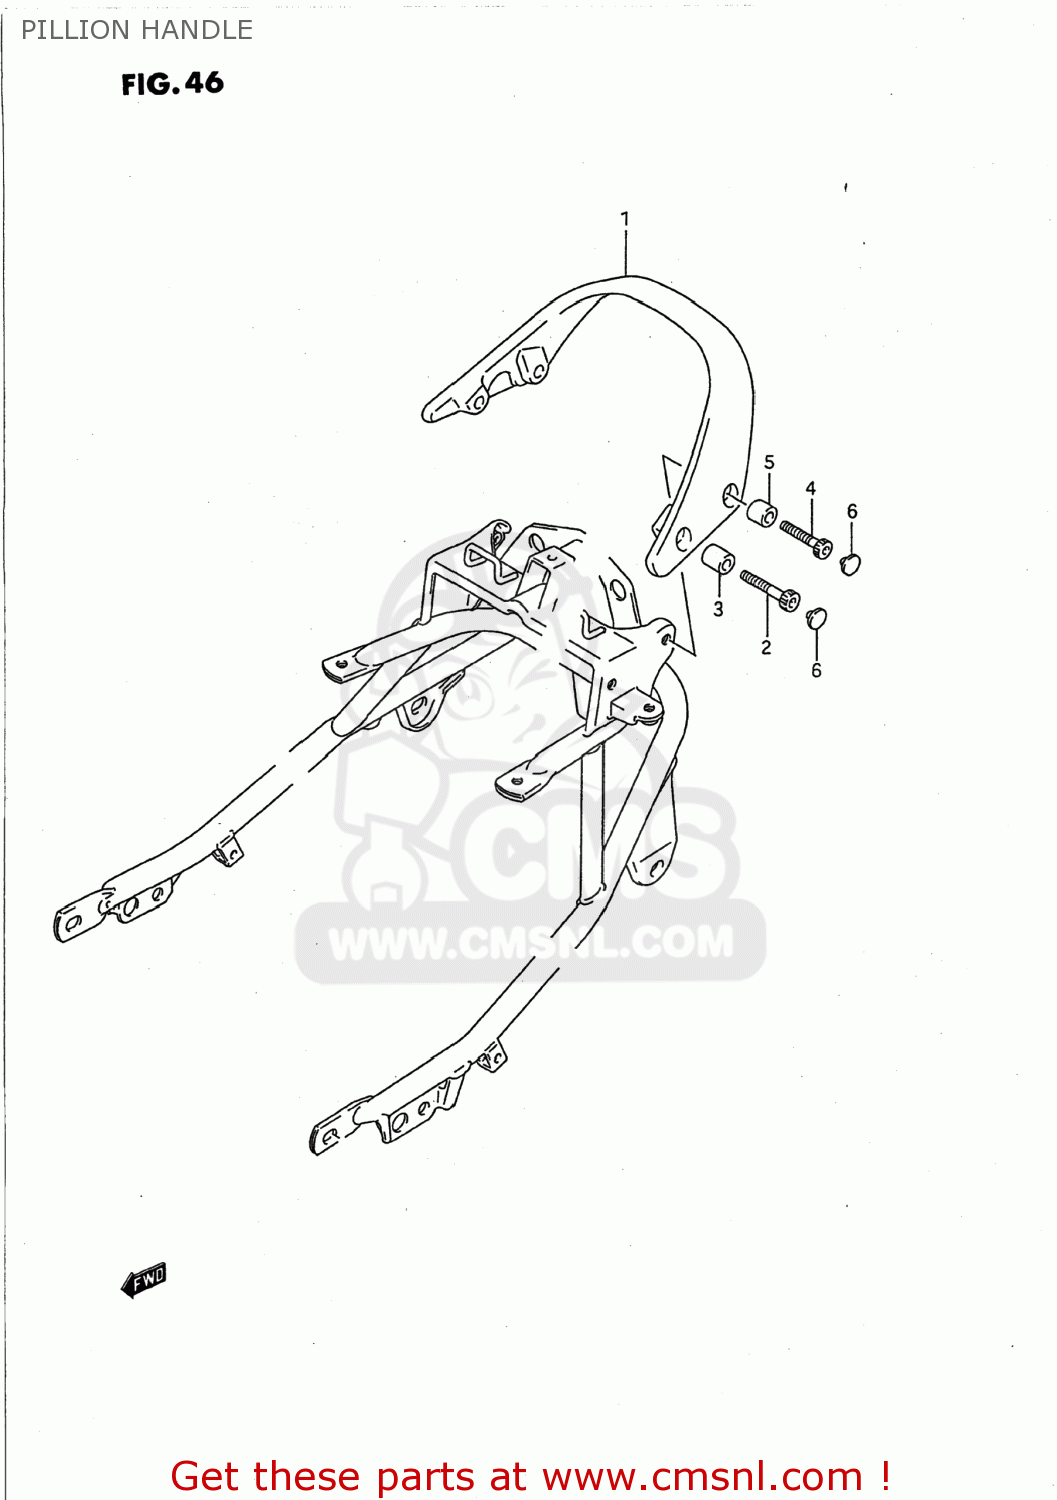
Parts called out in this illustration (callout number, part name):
1	HANDLE,PILLION RIDER
2	BOLT
3	SPACER(8.1X16X17)
4	BOLT
5	SPACER (10.2X16X12)
6	CAP(OD:14.5)
